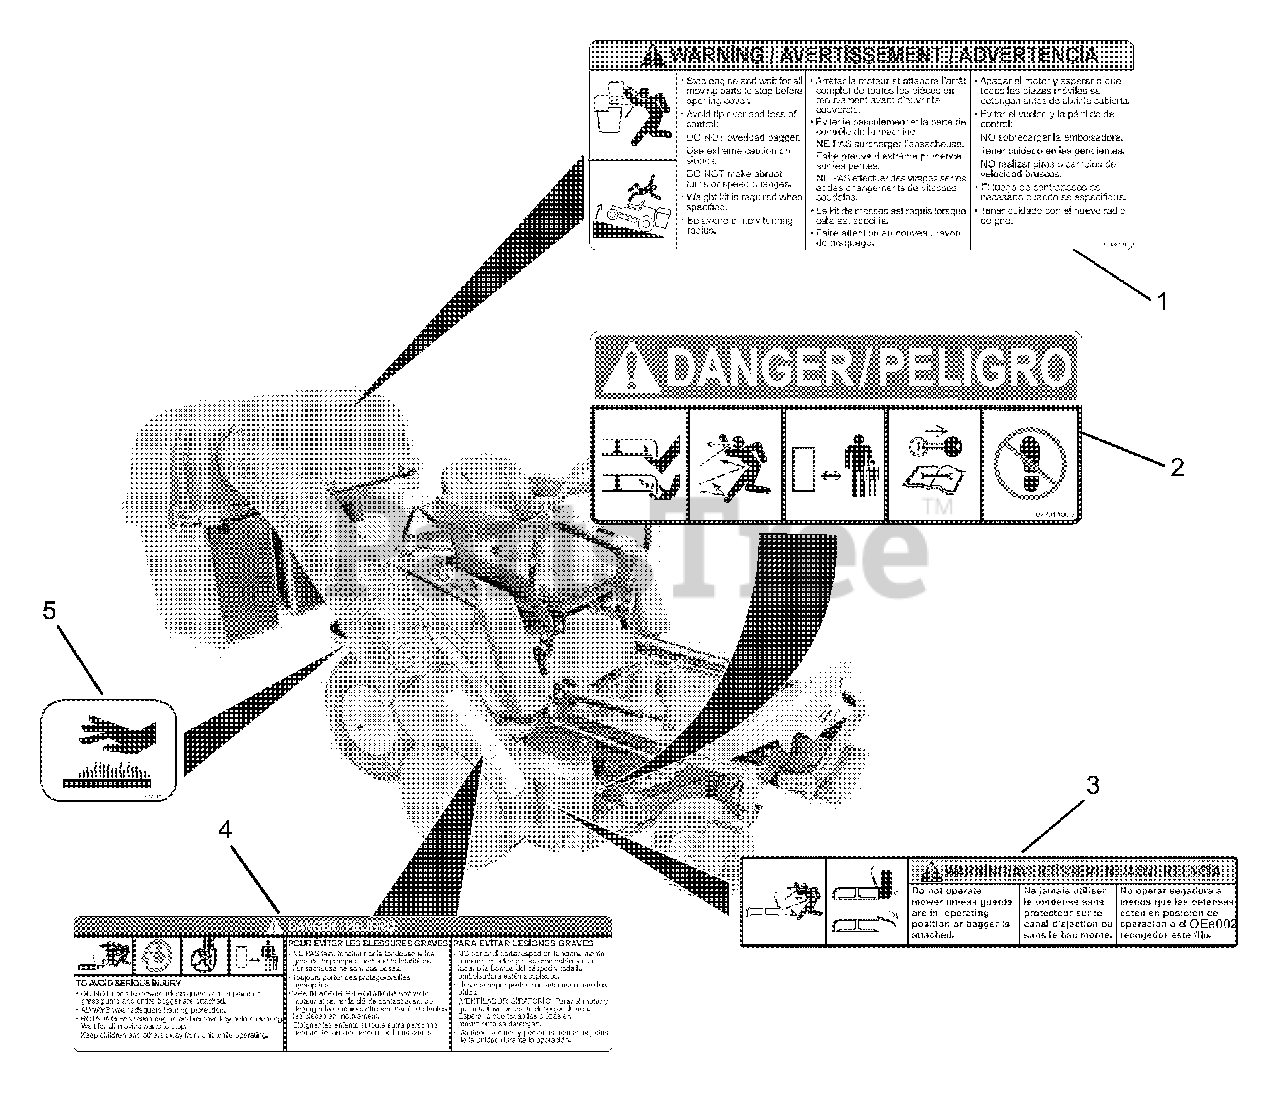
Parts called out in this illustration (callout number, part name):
1	Bagger Cover Decal
2	Mower Pan Danger Decal
3	Warning Decal
4	Grass Pump Caution Decal
5	Decal, Hot Surface
